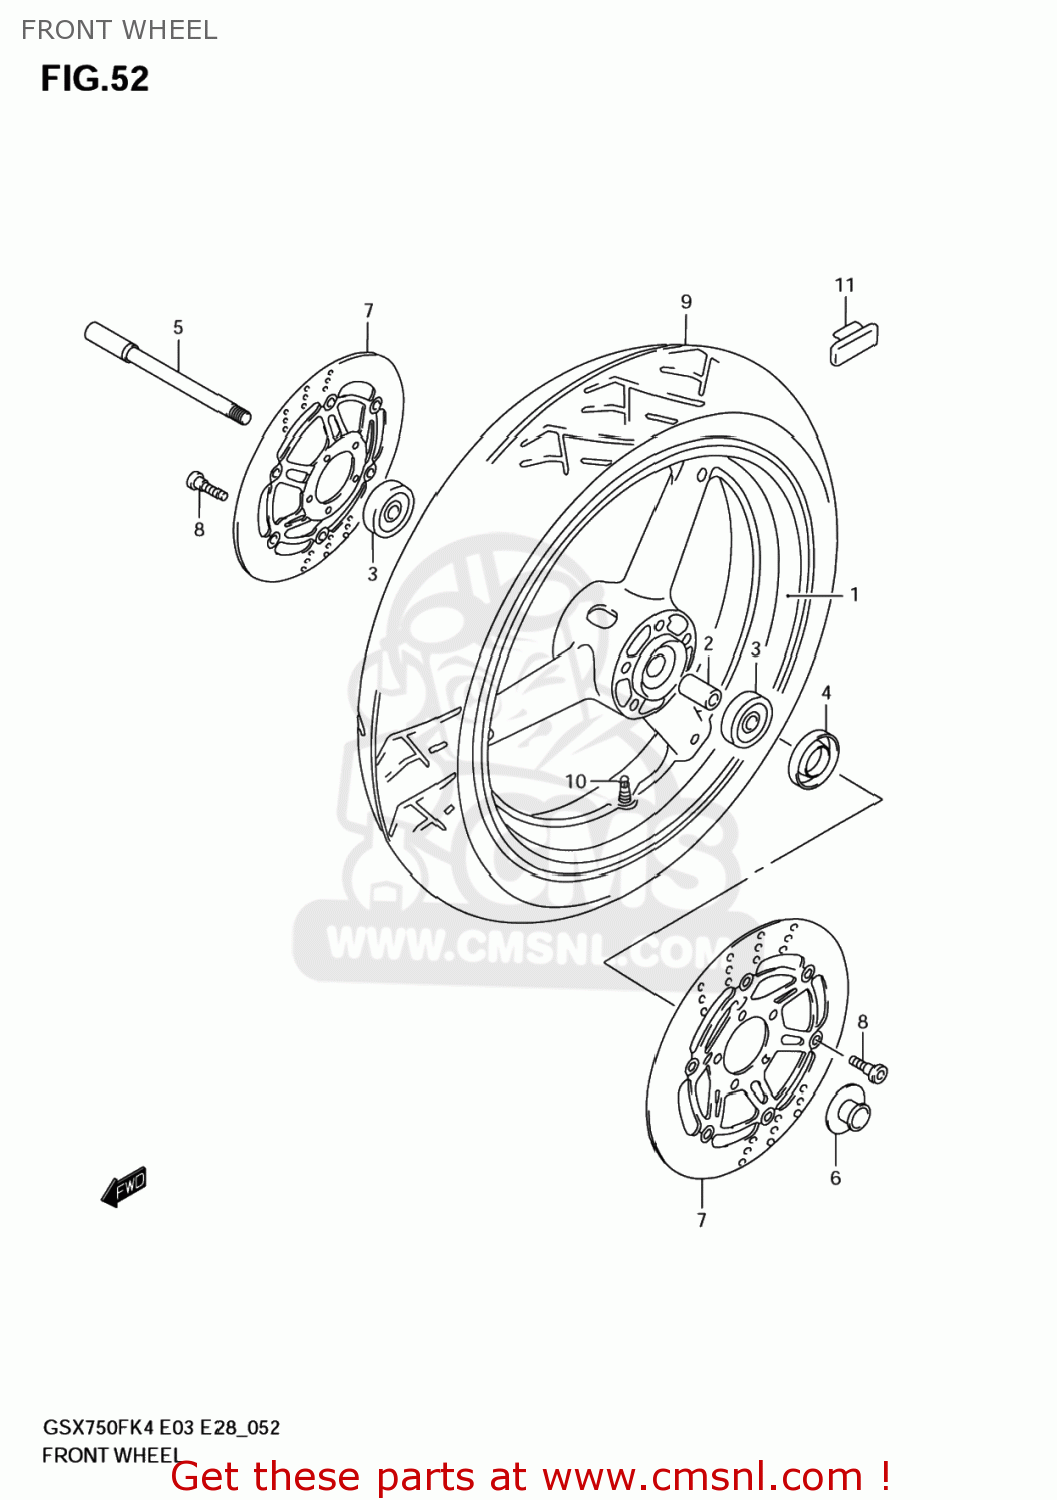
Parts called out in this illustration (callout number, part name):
1	WHEEL,FR(17M/CXMT3.50)
2	SPACER(17.5X25X88)
3	BEARING
4	SEAL,OIL(22X40X7)
5	AXLE,FR
6	SPACER,FR AXLE,L
7	DISC,FRONT BRA
8	BOLT(8X21)
9	TIRE,FR(120/70 ZR17 58W)
10	VALVE ASSY,WHEEL RIM(TR412)
11	BALANCER,WHEEL(10G)
